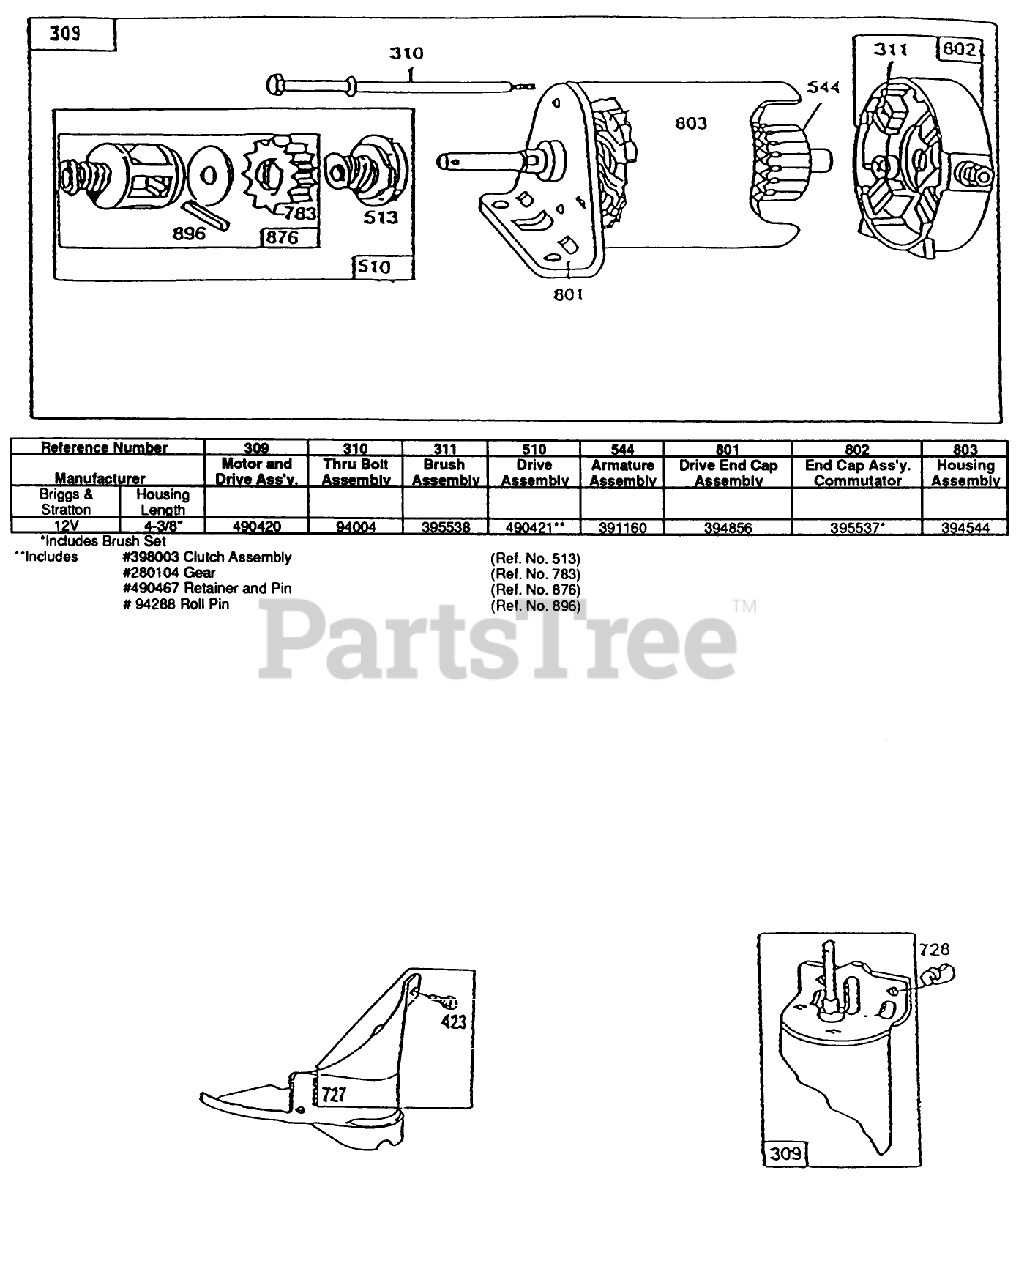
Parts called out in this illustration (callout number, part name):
309	Motor-Starting (12 Volt)
423	Screw
727	Cover-Starter (Includes Mounting Screws)
728	Crew
